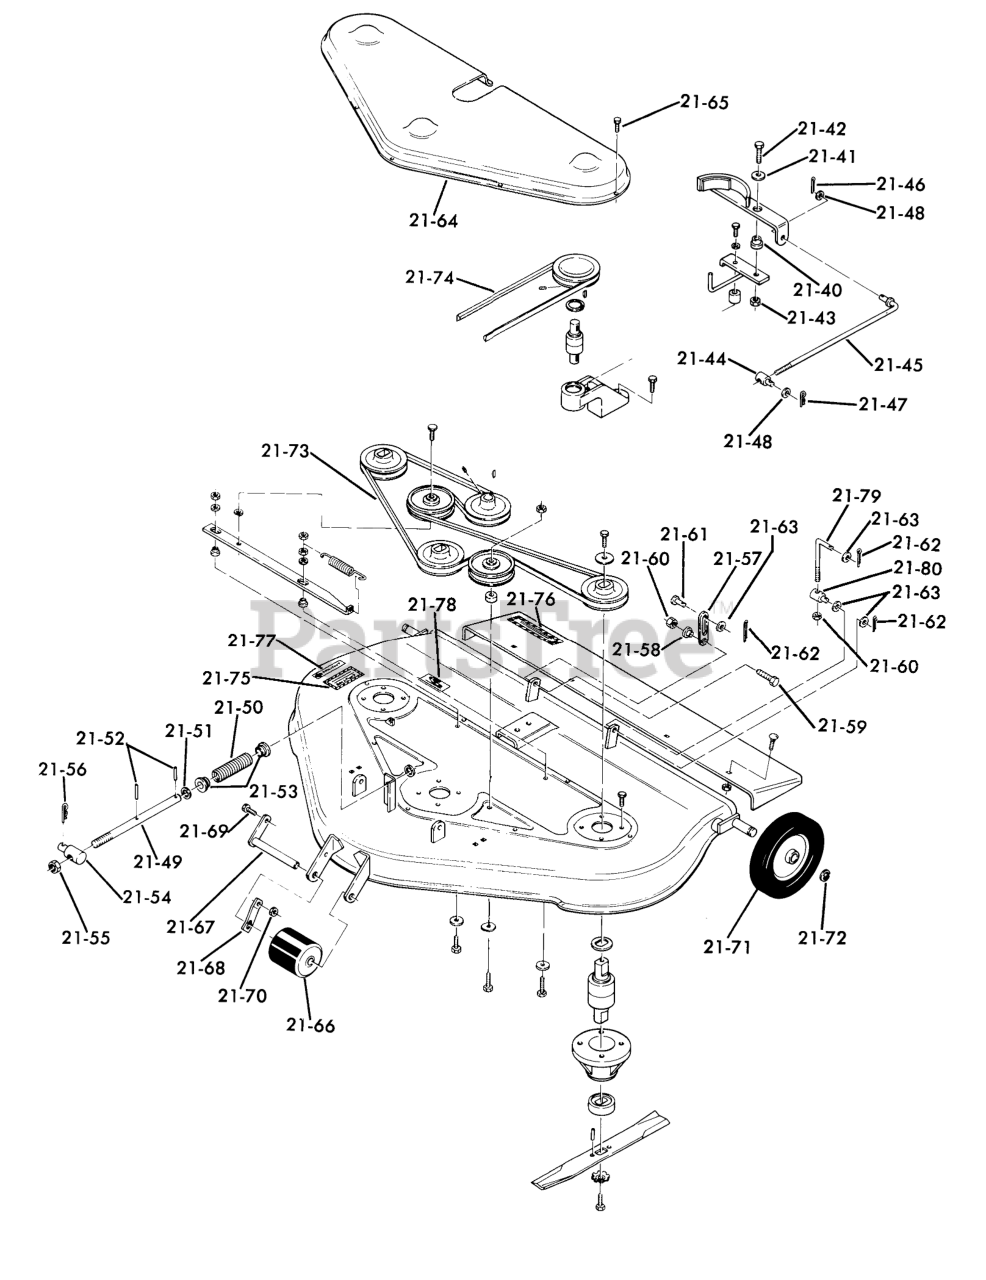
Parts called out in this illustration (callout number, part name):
21-40	SPACER
21-41	WASHER
21-42	BOLT
21-43	Nut
21-44	TRUNNION
21-46	Cotter Pin
21-47	Hairpin Cotter
21-48	Washer
21-49	Link Rod
21-50	SPRING
21-51	WASHER
21-52	SPIROL PIN
21-53	BUSHING
21-54	Trunnion
21-55	Hex Nut 7/16-14
21-56	Hairpin Cotter
21-57	BAR-LIFT LINK R
21-58	SPACER-LIFT LINK
21-59	Bolt
21-60	Nut
21-61	CLEVIS PIN
21-62	Cotter Pin
21-63	Washer
21-64	Belt Cover
21-65	Bolt
21-66	Roller
21-67	Roller Shaft
21-68	SPRING ROLLER STOP
21-69	H H C S
21-70	Nut
21-71	Wheel
21-72	E Ring
21-73	80" Mower Belt
21-74	BELT-40IN DRIVE
21-75	Caution Decal
21-76	Guard Decal
21-77	Decal-Edge of Cut
21-78	Belt Installation Decal
21-79	ROD-LIFT
21-80	STUD-LIFT
